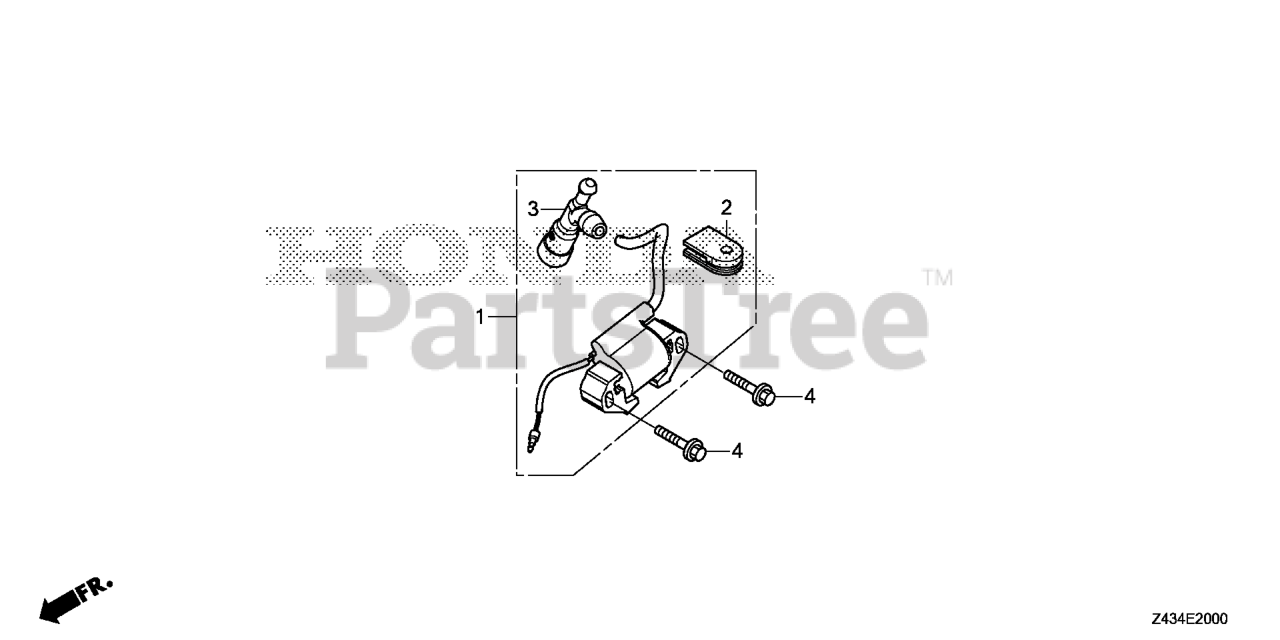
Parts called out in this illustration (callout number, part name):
1	COIL ASSY., IGNITION
2	GROMMET, IGNITION WIRE
3	CAP ASSY., NOISE SUPPRESSOR (TEC)
4	BOLT, FLANGE (6X32)
